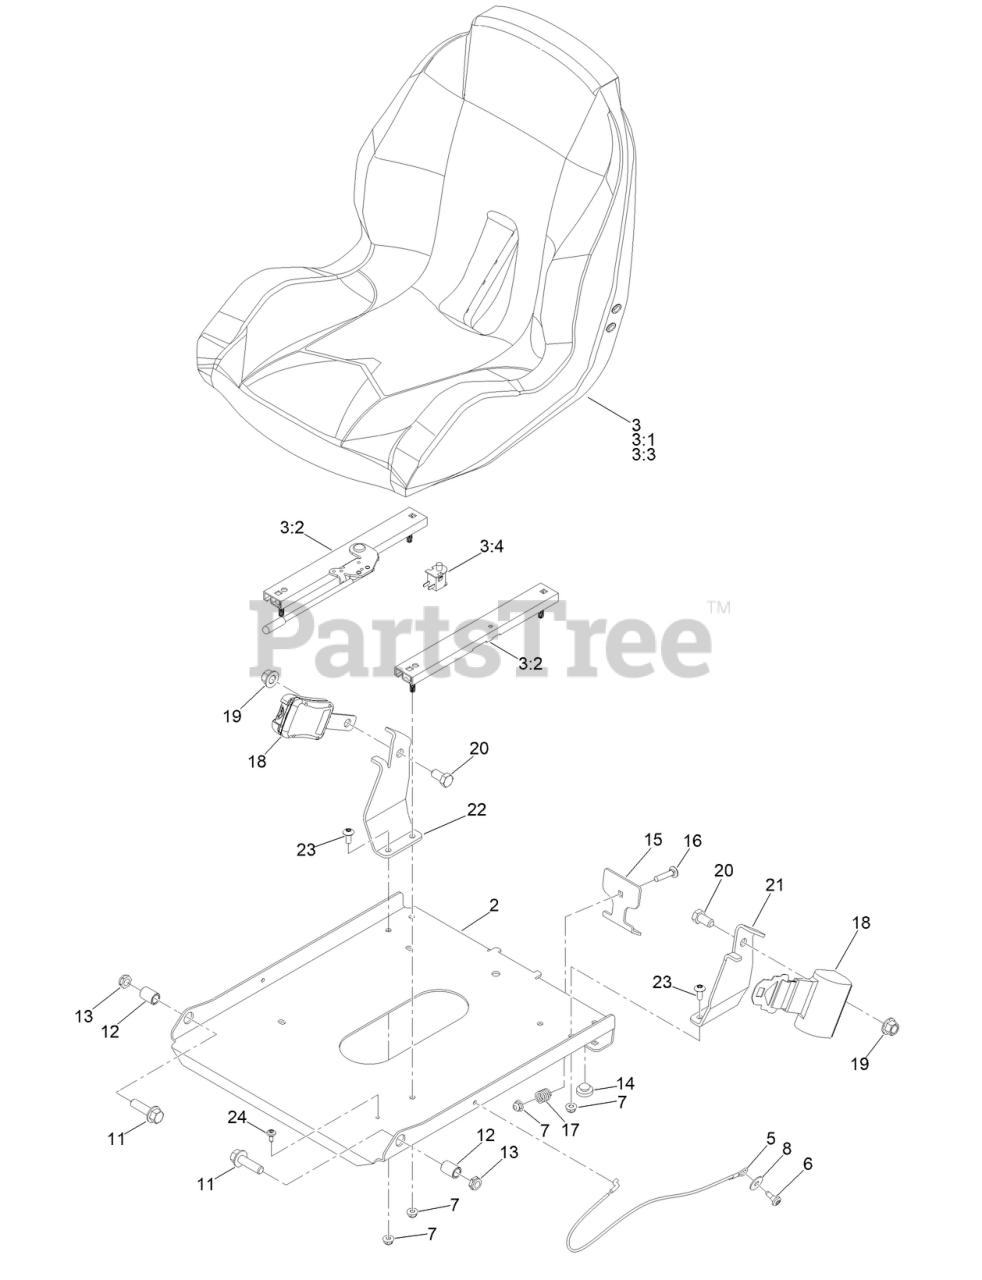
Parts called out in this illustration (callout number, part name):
2	PAN-SEAT, LOWERED
3	SEAT ASM - SK130
3:1	SEAT-DEFENDER
3:2	SLIDE-ASM
3:3	COVER-SEAT
3:4	SWITCH-BAIL
5	CABLE-LANYARD
6	SCREW-SHOULDER
7	NUT-HF
8	WASHER-FLAT
11	SCREW-HHF
12	BUSHING-PIVOT, SEAT
13	NUT-HEX
14	BUMPER-SEAT
15	BRACKET-LATCH, SEAT
16	BOLT-CARR
17	SPRING-COMPRESSION
18	SEAT BELT KIT
19	NUT-HF
20	SCREW-HH
21	BRACKET-SEATBELT, LH
22	BRACKET-SEATBELT, RH
23	SCREW-TORX
24	SCREW-SHOULDER
